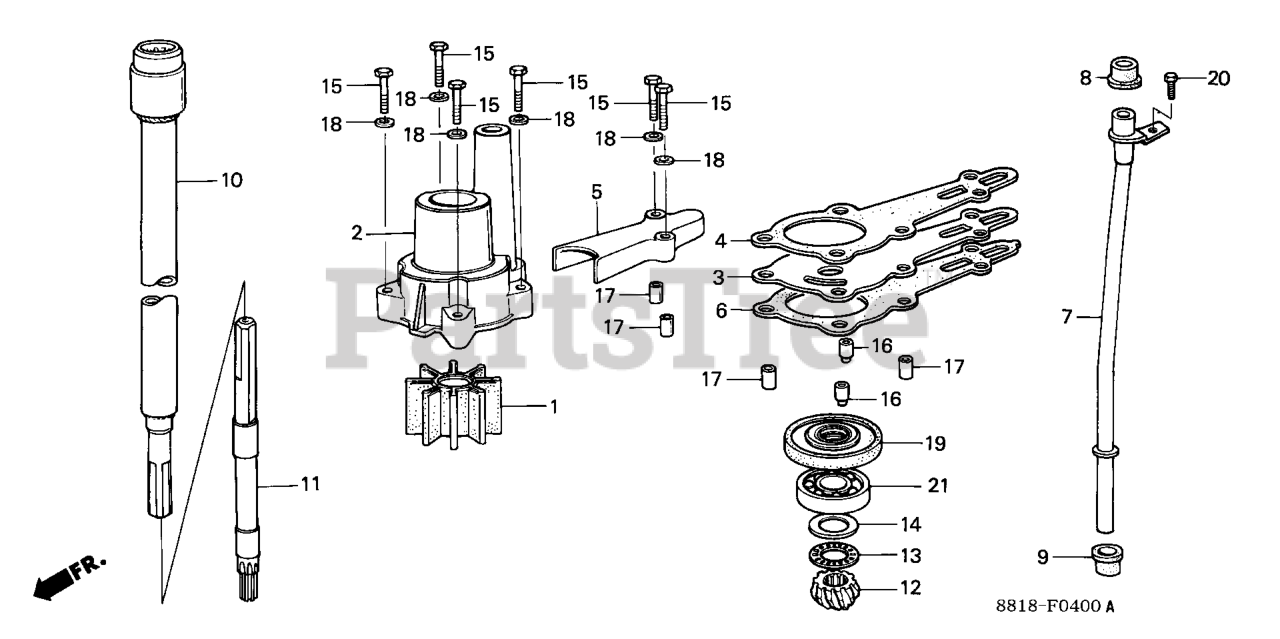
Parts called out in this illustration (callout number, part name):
1	IMPELLER, PUMP
2	HOUSING, IMPELLER
3	COVER, IMPELLER
4	GASKET A, IMPELLER
5	HOLDER, IMPELLER COVER (NOT AVAILABLE)
6	GASKET B, IMPELLER
7	TUBE, WATER (S)
8	RING, WATER TUBE SEAL
9	RING, SEAL
10	SHAFT, VERTICAL (S)
11	SHAFT, PINION
12	PINION, BEVEL
13	BEARING, THRUST (15MM)
14	WASHER A, THRUST BEARING (2.00MM)
14	WASHER B, THRUST BEARING (2.05MM)
14	WASHER C, THRUST BEARING (2.10MM)
15	BOLT, HEX. (6X28)
16	COLLAR B, DISTANCE
17	COLLAR A, DISTANCE
18	WASHER, PLAIN (6MM) Use from Frame SN 4800713.
19	SEAL, WATER (15MM) (NOK)
20	BOLT, HEX. (6X12)
21	BEARING, RADIAL BALL (6302)
